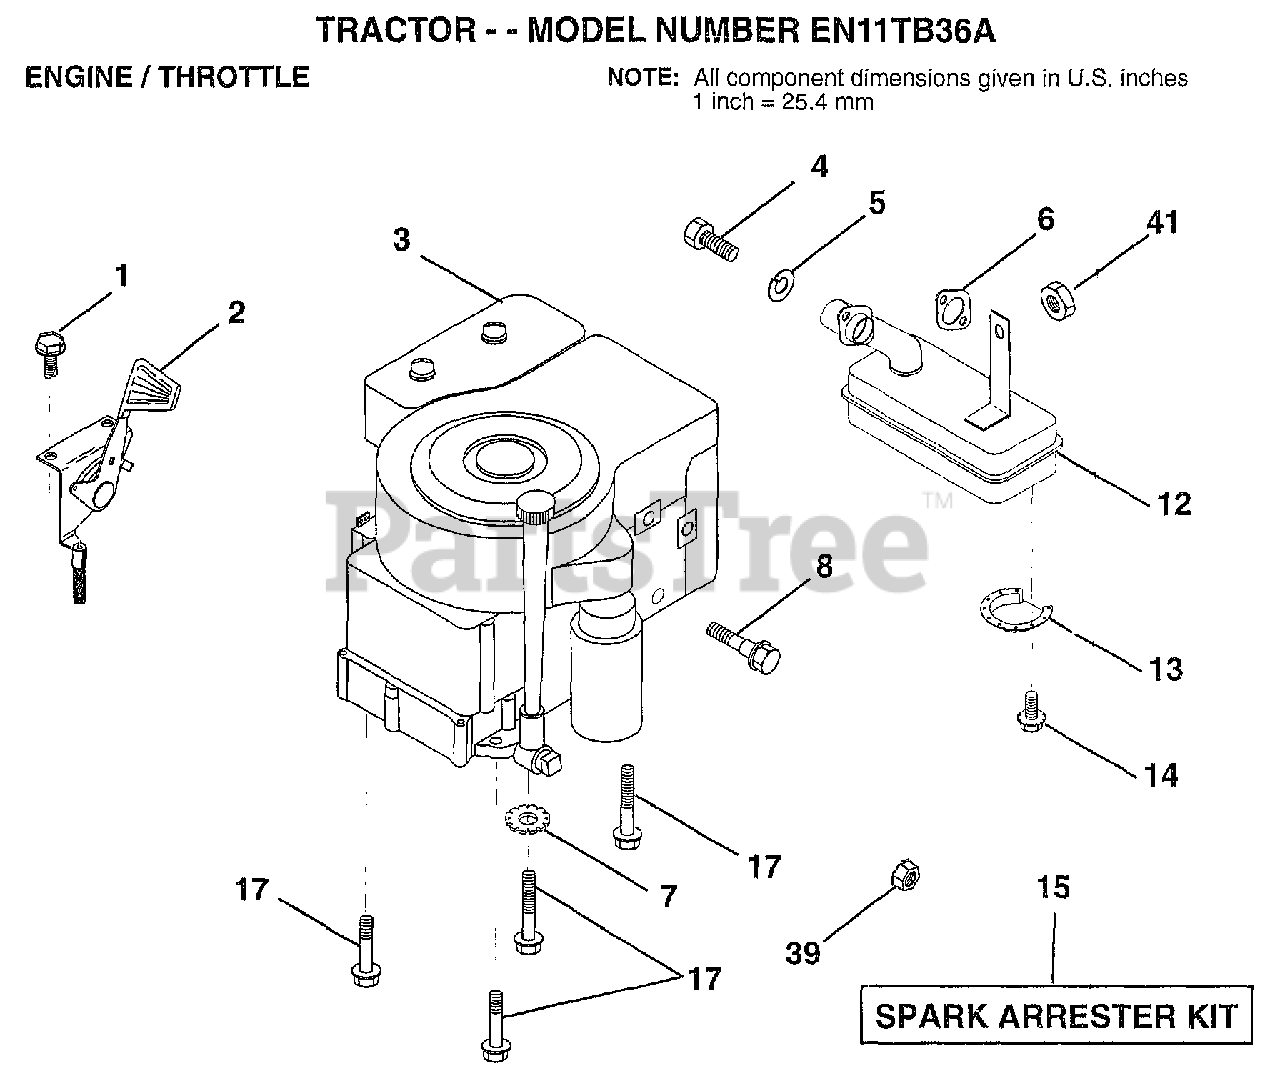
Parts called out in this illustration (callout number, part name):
1	SCREW LT
2	"CONTROL,THROTTLE"
4	SCREW HEX HD CAP
5	LOCKWASHER
7	LOCKWASHER
8	SHOULDER BOLT ST
12	MUFFLER-TECH 13HP
13	DEFLECTOR.222573
17	SCREW LT
39	NUT
41	"NUT HEX,LOCK,FLAN"
